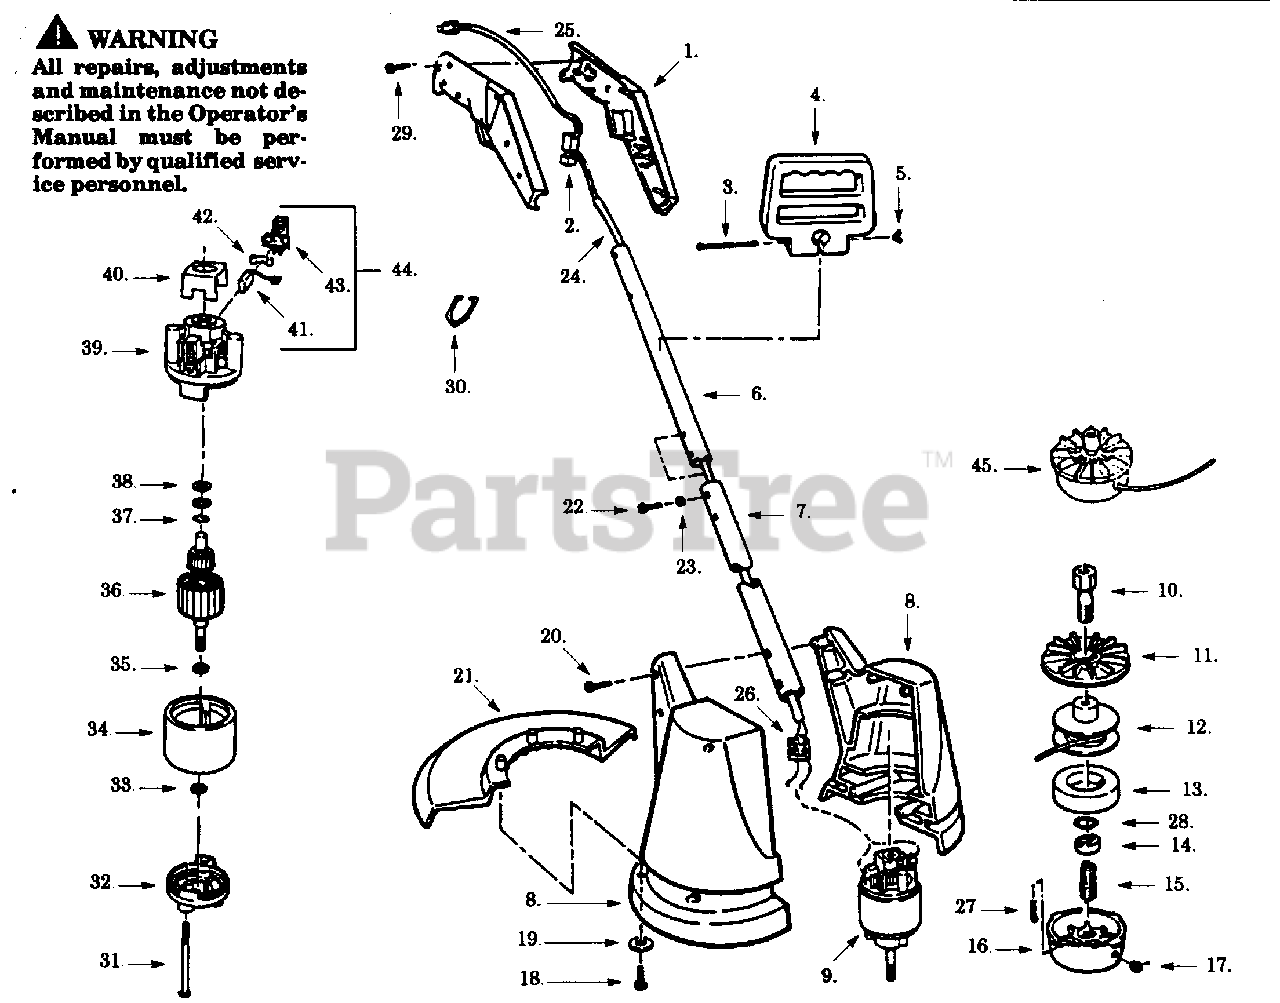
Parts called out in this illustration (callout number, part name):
1	R.H./L.H. Handle
2	Trigger Switch
4	Side Handle
5	Wing Nut
6	Upper Handle Tube
7	Lower Handle Tube
8	R.H./L.H. Housing
10	Drive Adapter
11	Rear Plate
12	Spool & Line
13	Foam Pad
14	Drive Adapter Nut
21	Line Cutter Guard
25	Power Cord
26	P.C. Bridge Kit
27	Cotter Pin
32	Endbell Output
34	Field Ass'y.
35	Retainer Ring
36	Armature
37	Retainer Ring
39	Endbell (Brush)
40	Insulator
43	Brush Holder
44	Brush Kit (Incl. 41,42,43)
45	Cutting Head Ass'y.
